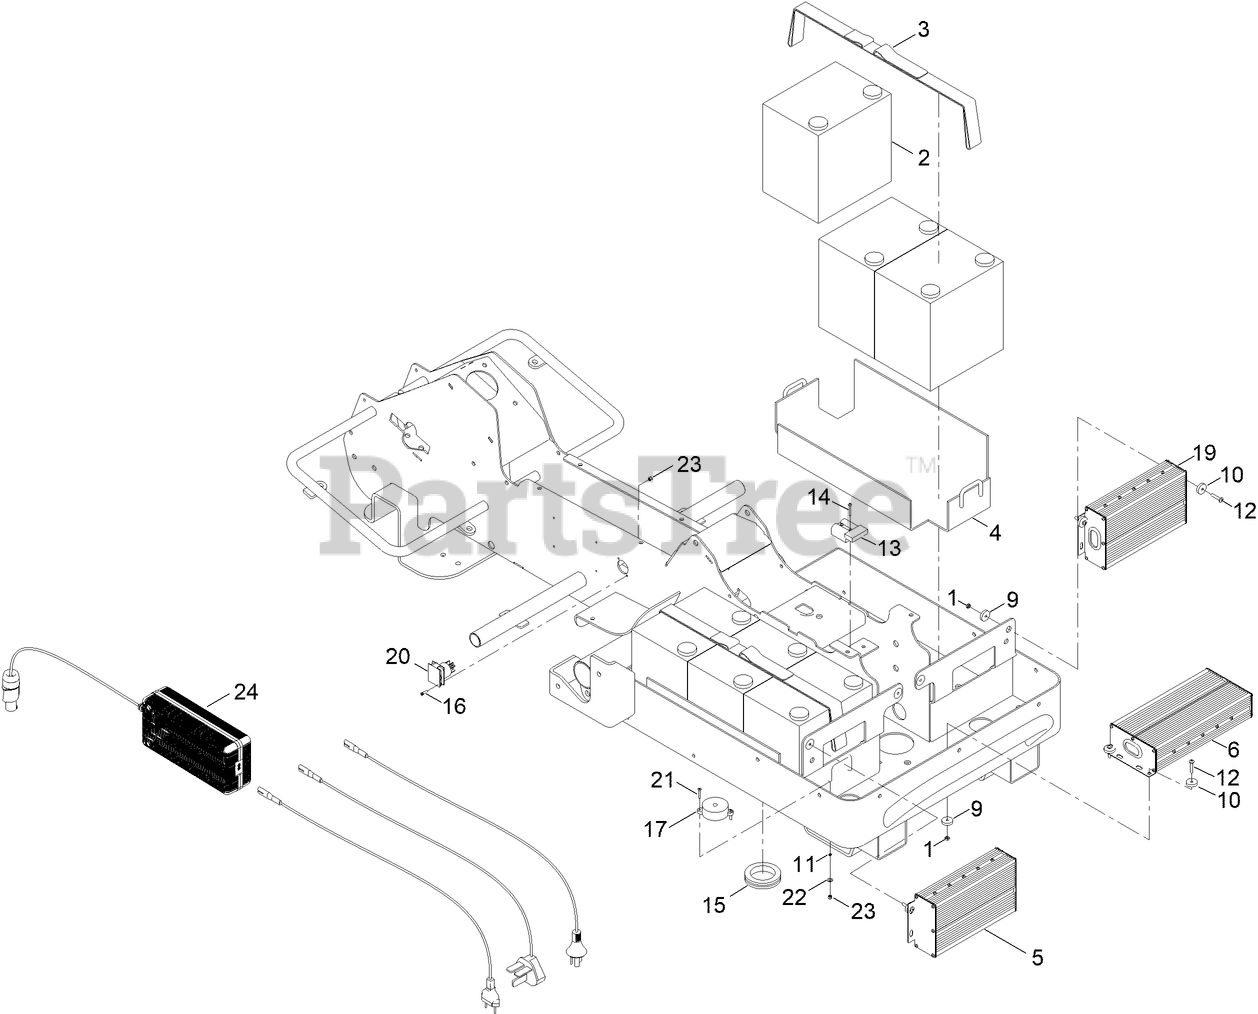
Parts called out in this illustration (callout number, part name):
2	BATTERY
3	STAP, BATTERY
4	HOLDER, BATTERY
5	CUTTING CONTROLLER
6	DRIVING CONTROLLER
9	FLAT BUSH, RUBBER
10	BUSH, RUBBER
11	SPRING WASHER
13	CONNECTOR, ELECTRICAL
15	INSERT, RUBBER CABLE LARGE
19	CUTTING CONTROLLER
20	POWER CONNECTOR ASM
22	WASHER-PLAIN
23	NUT-NYLOC
24	CHARGER
